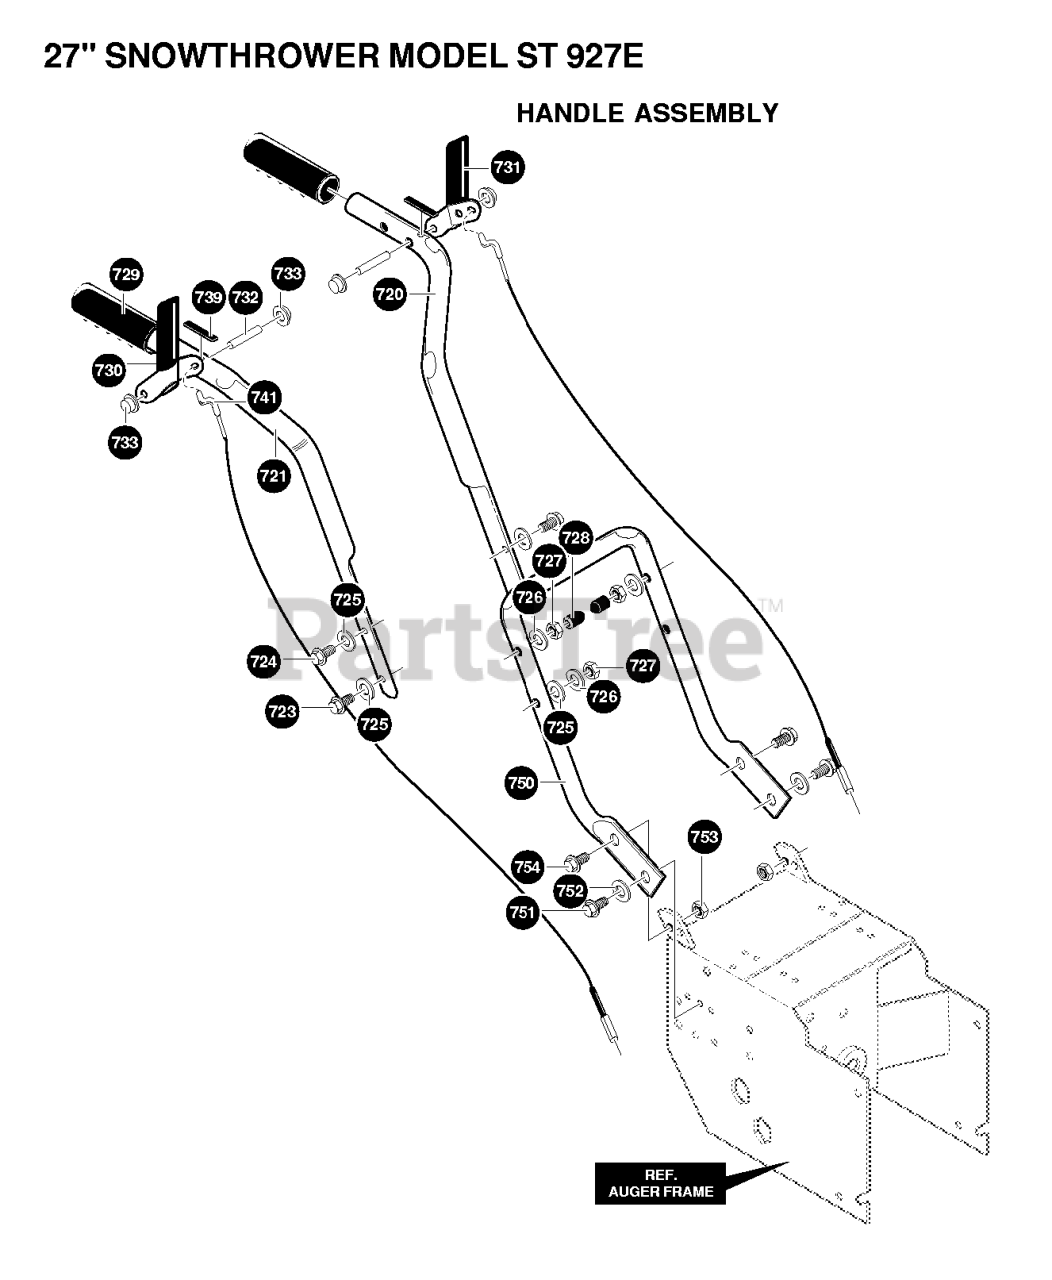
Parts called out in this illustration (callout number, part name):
720	UPPER HANDLE, LH
721	UPPER HANDLE, RH
725	WASHER, FLAT .406X .81X.
726	WASHER, REGSPTLK.393X.68X
727	NUT, 3/8-16 REGHXCTRLK
729	HANDLE GRIP
730	HANDLE-CLUTCH
731	ASSY, CLUTCH LEVER LH
733	NUT, PUSH ON CAP .312 OD
739	BUMPER, RECT W/FLAT TOP
741	CABLE, CLUTCH 31.75" TRACTION
750	LOWER HANDLE
751	SCREW, 5/16-18X .75 WAHHT
752	WASHER, HVSPTLK .328X.60X
753	NUT, 5/16-18 REGHEXCTRLK
754	SCREW, 5/16-18X .75 WAHHT
